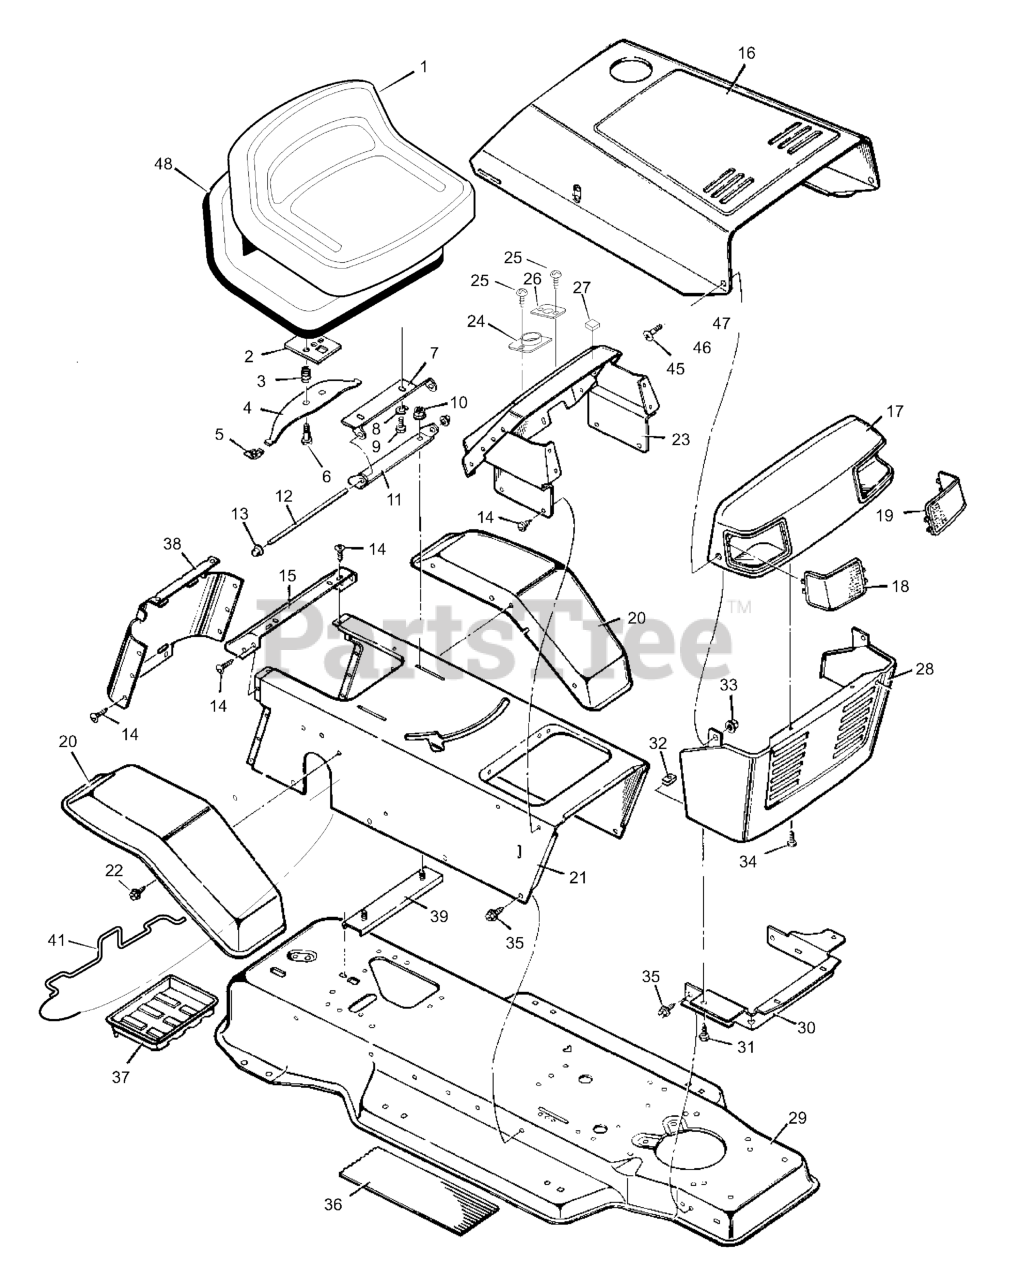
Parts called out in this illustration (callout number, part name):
2	Plate Assembly, Switch
3	Spring, Compression
4	Spring, Seat
5	Glide, Spring
6	Bolt, Shoulder
7	Support, Seat
8	Lockwasher
9	Bolt, Hex
10	Locknut, Flange
11	Bracket, Pivot
12	Rod, Pivot
13	Cap, Push On
14	Screw, Tap
15	Fender, Apron
17	Grille, Upper
18	Lens, Right
19	Lens, Left
21	Console Assembly
23	Dash Panel
24	Bearing, Steering
26	Bearing
27	Bumper
28	Grill, Lower
29	Frame Assembly
30	Support, Grill
33	Locknut, Flange
34	Fastener, Plastic
37	Tray, Battery
38	Cap, Console
39	Channel Assembly
41	Clamp, Battery
45	Bolt, Shoulder
48	Pan, Seat (with foam)
